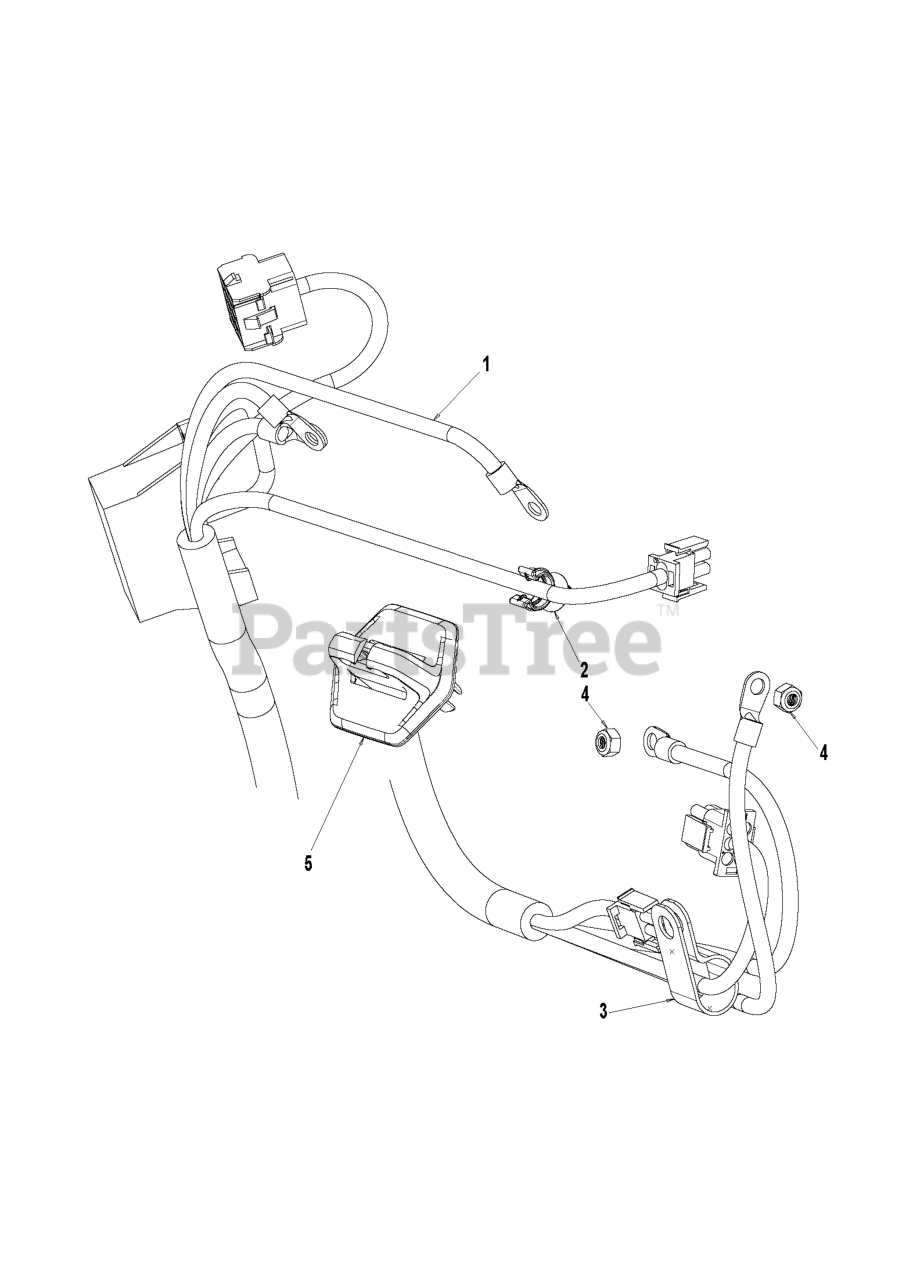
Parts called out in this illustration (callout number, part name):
2	CLIP CONVOLUTED TUBE, 1/4 BLAC
3	CLIP.CABLE.BLK
4	NUT LOCK NUT M6 NYLOC INSERT H
